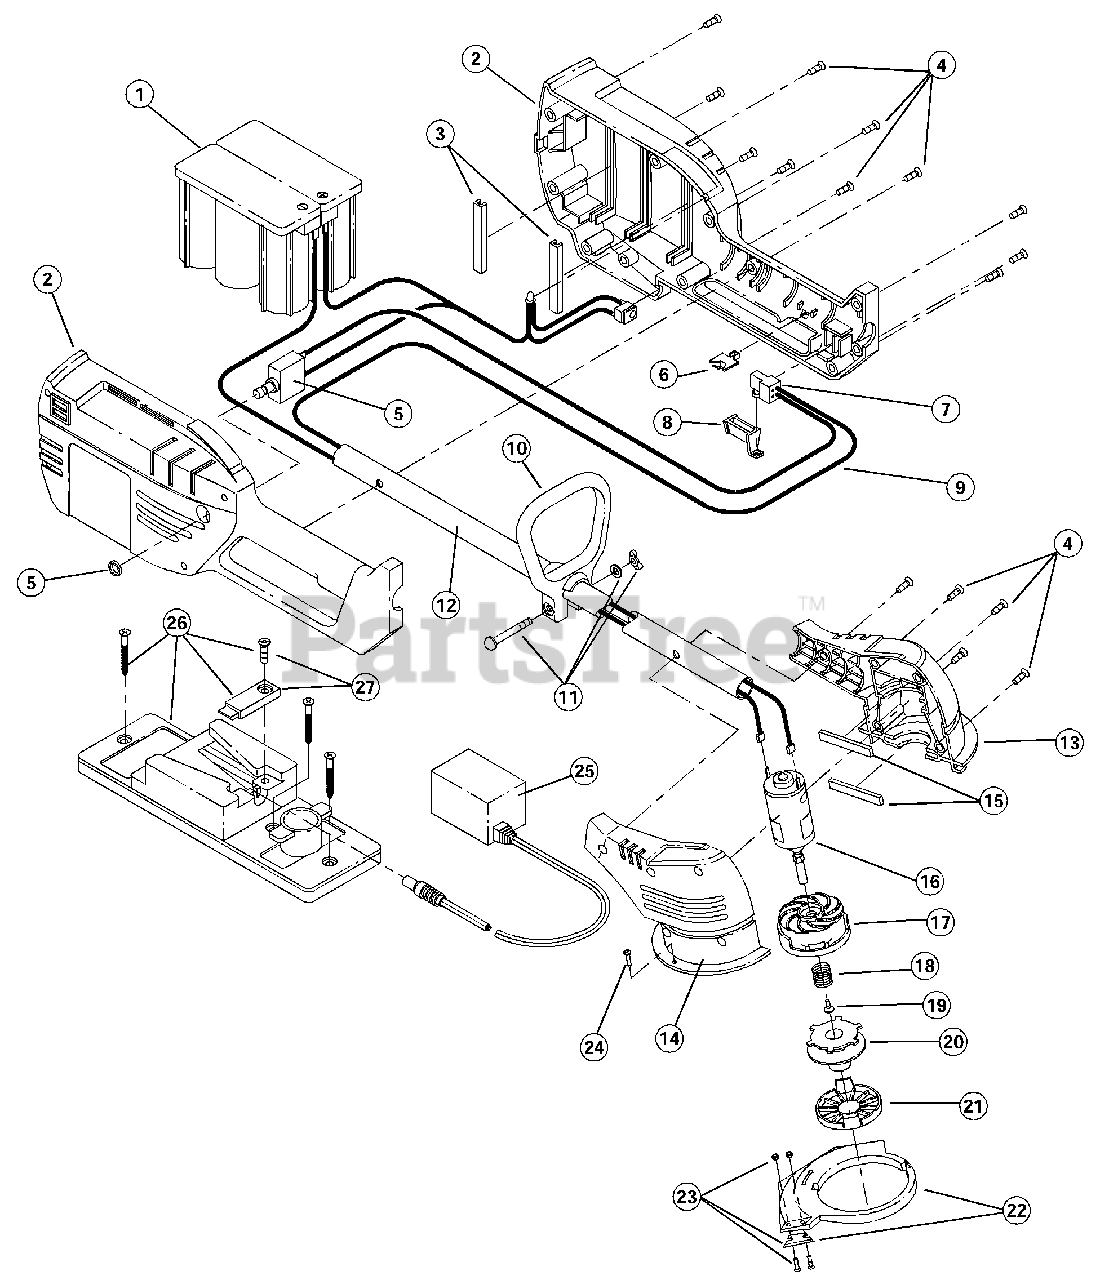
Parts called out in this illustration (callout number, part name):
1	Battery
2	Battery Housing
3	Battery Cushions (qty. 5)
4	Housing Screw Set
5	Thermal Overload Switch
6	Lock-Out Button
7	Switch
8	Trigger
9	Wiring Harness Assembly
10	D-Handle
11	Handle Hardware
12	Motor Wires Tube
13	Left Motor Housing
14	Right Motor Housing
15	Motor Supports
16	Motor Assembly
17	Outer Spool and Eyelet
20	Inner Reel
21	Reel Cover
22	Guard and Blade Assembly
23	Blade Assembly
24	Guard Screw
25	12 Volt Charger
26	Charging Station Stand
27	Barrel Clamp Assembly
